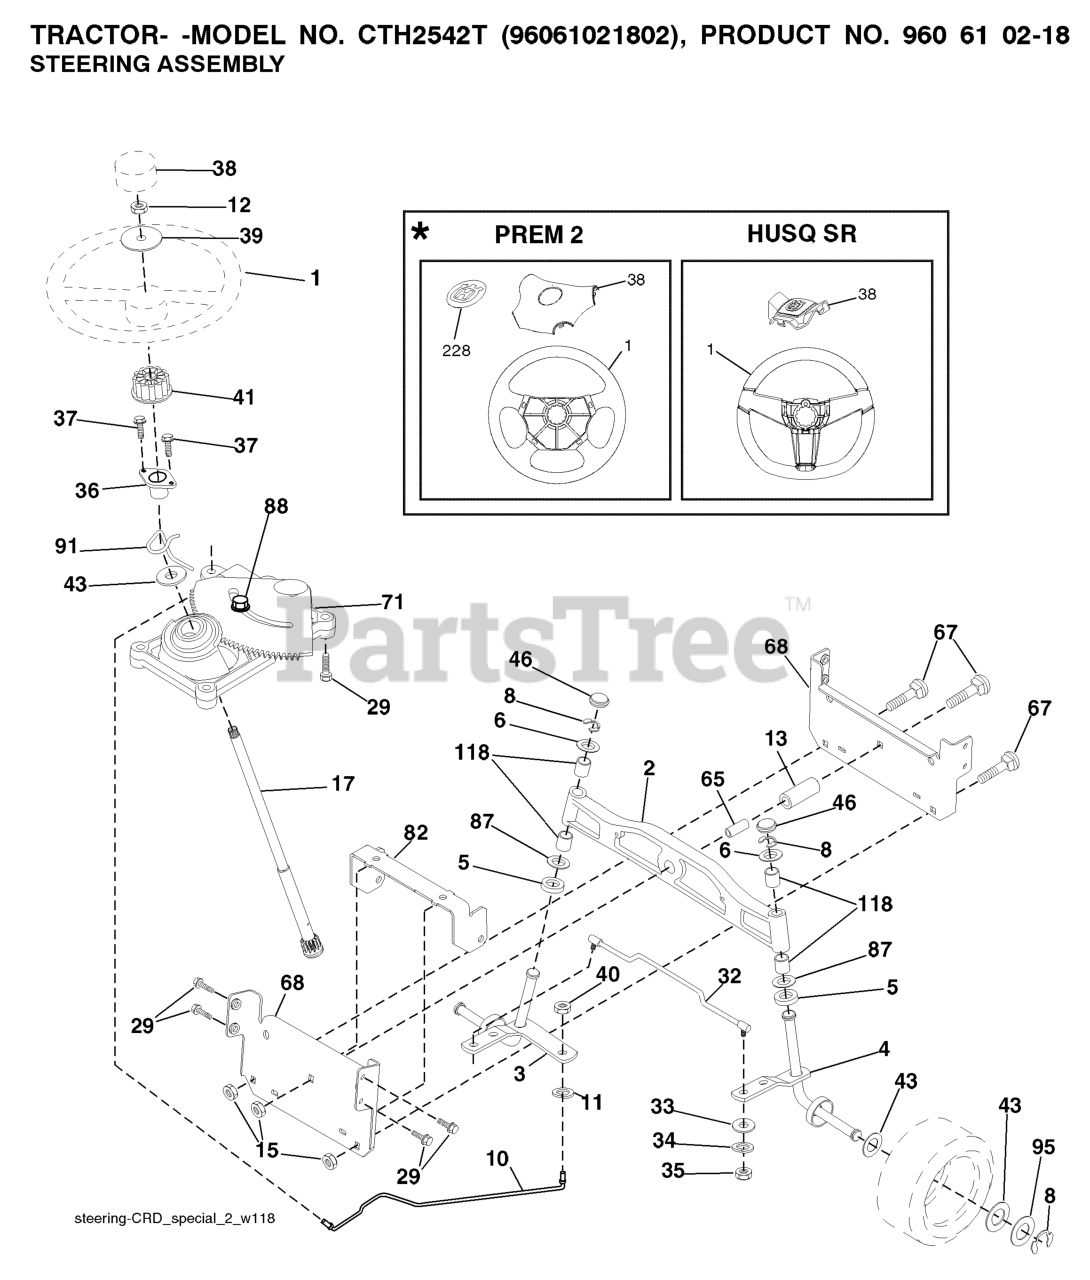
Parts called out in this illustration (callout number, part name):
1	RP WHEEL.STEER.HUSQ.PREM.OVMLD
2	AXLE.ASM.LT.CAST.LGHTWGHT
3	SPINDLE.ASM.LH.15"TIRES
4	SPINDLE.ASM.RH.15"TIRES
5	THRUST WASHER
10	DRAGLINK.15".TIRES.2001
11	WASHER, LOCK 3/8
12	NUT.HEX.1/2-20
13	TUBE, PIVOT AXLE
15	NUT
17	SHAFT ASM STRG
29	SCREW, 3/8-16X3/4
33	WASHER M
34	WASHER.LOCK.HVY.HLCL.SPR.5/16
35	NUT, CROWNLOCK
36	BUSHING, STRG. BLK
37	SCREW.TT.#10-32X.5.3/8.FLANGE
38	RP INSERT.CAP.WHL.STRG.HUSQ.
39	WASHER 9/16"ID, 2 3/8"OD
40	NUT CROWNLOCK 3/8-24
41	ADAPTER, WHEEL STNG..
46	CAP.SPINDLE.BLACK
65	SPACER.BRACE.AXLE
67	BOLT CARRIAGE
68	BRACE.AXLE.15"TIRES
71	STEERING ASM
82	BRACKET.SUSP.CHASSIS.FRONT.15
87	WASHER, FLAT .781 X 1 1/2"
88	BOLT, SHOULDER 7/16-20
91	CLIP.STEERING
95	WASHER.HARDENED
118	BUSHING, AXLE CAST
